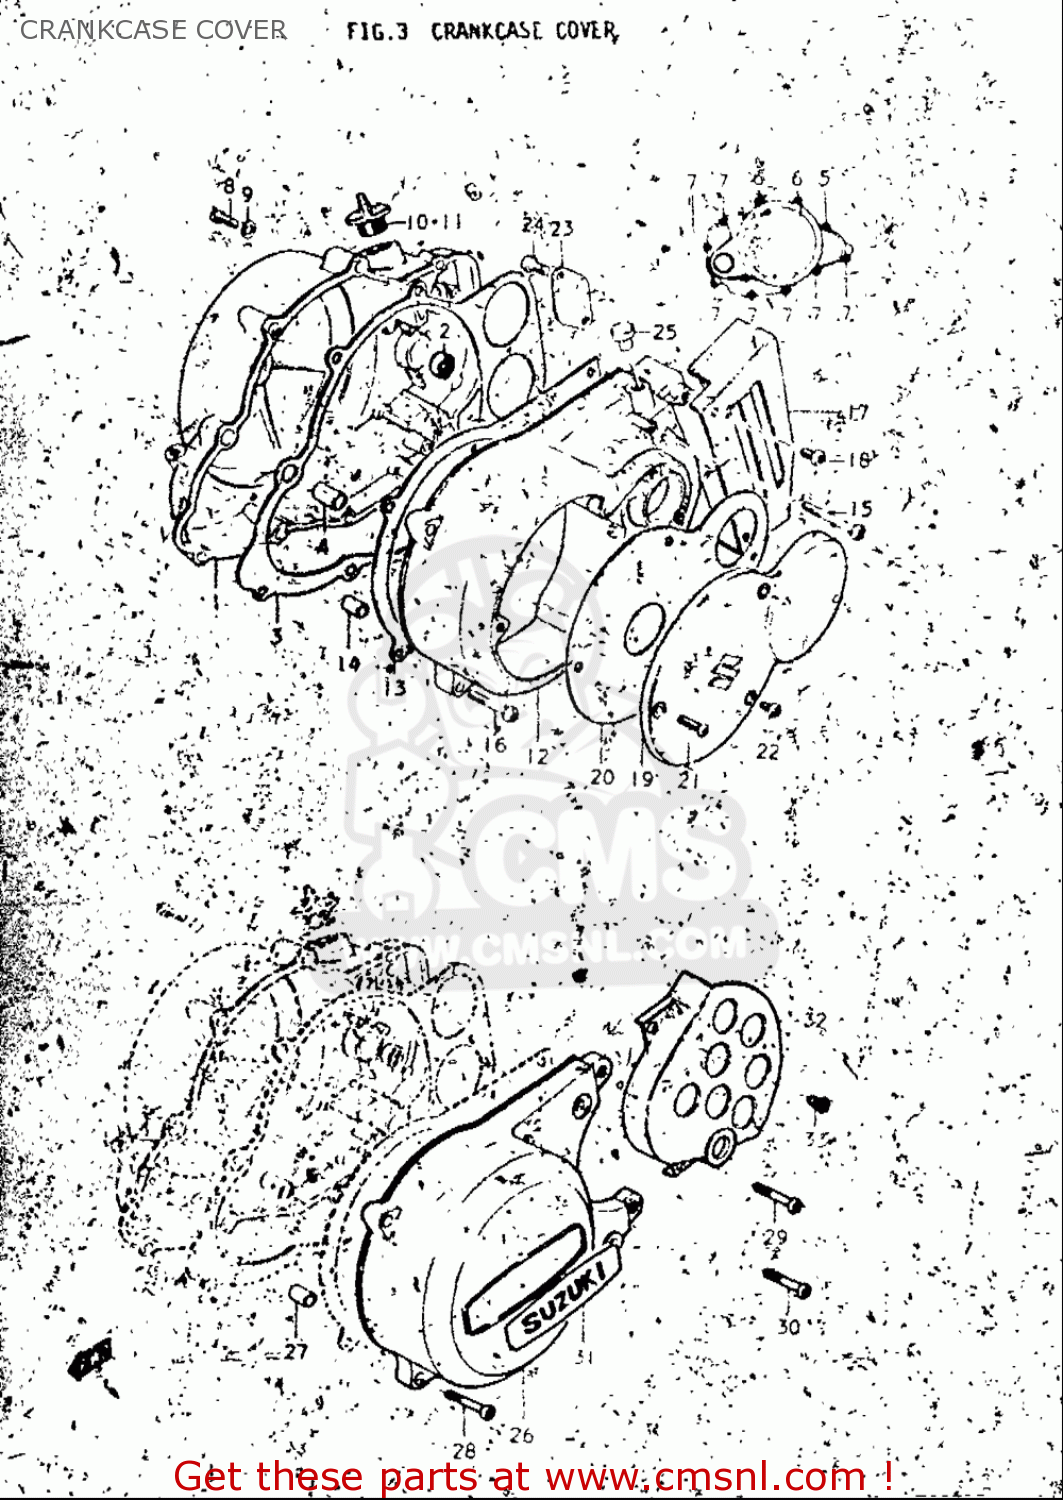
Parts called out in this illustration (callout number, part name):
3	GASKET,CLUTCH COVER (NAS)
4	PIN
5	SCREW
6	SCREW
7	SCREW
8	SCREW(6X10)
9	GASKET(6.2X11X1) (NAS)
10	PLUG SET
11	PLUG
13	GASKET,MAGNETO COVER (NAS)
14	PIN
15	SCREW
16	SCREW
18	SCREW
20	GASKET,MAGNETO INSPECTION (NAS)
21	SCREW
22	SCREW
24	SCREW
25	CAP
27	PIN
28	SCREW
29	SCREW
30	SCREW
33	SCREW
